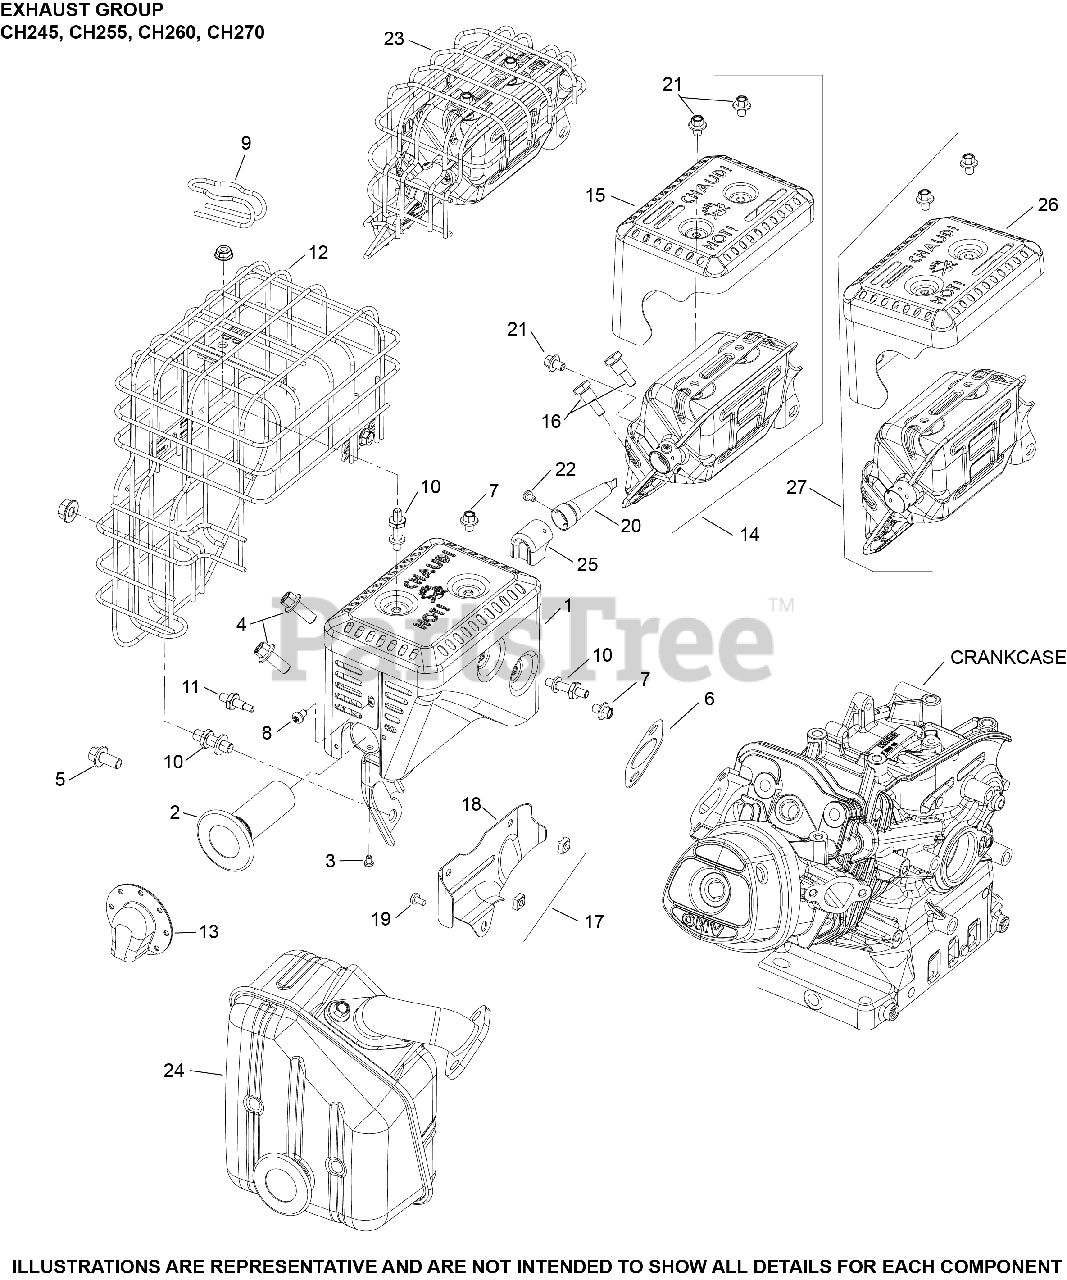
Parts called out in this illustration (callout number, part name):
3	SCREW, SPARK ARRESTOR
14	MUFFLER, ASSEMBLY
15	KIT, MUFFLER GUARD
16	SCREW, SHOULDER
20	SPARK ARRESTOR, ASSEMBLY
21	SCREW, M6 X 8 HEX FLANGE HEAD
25	TUBE, DEFLECTOR
